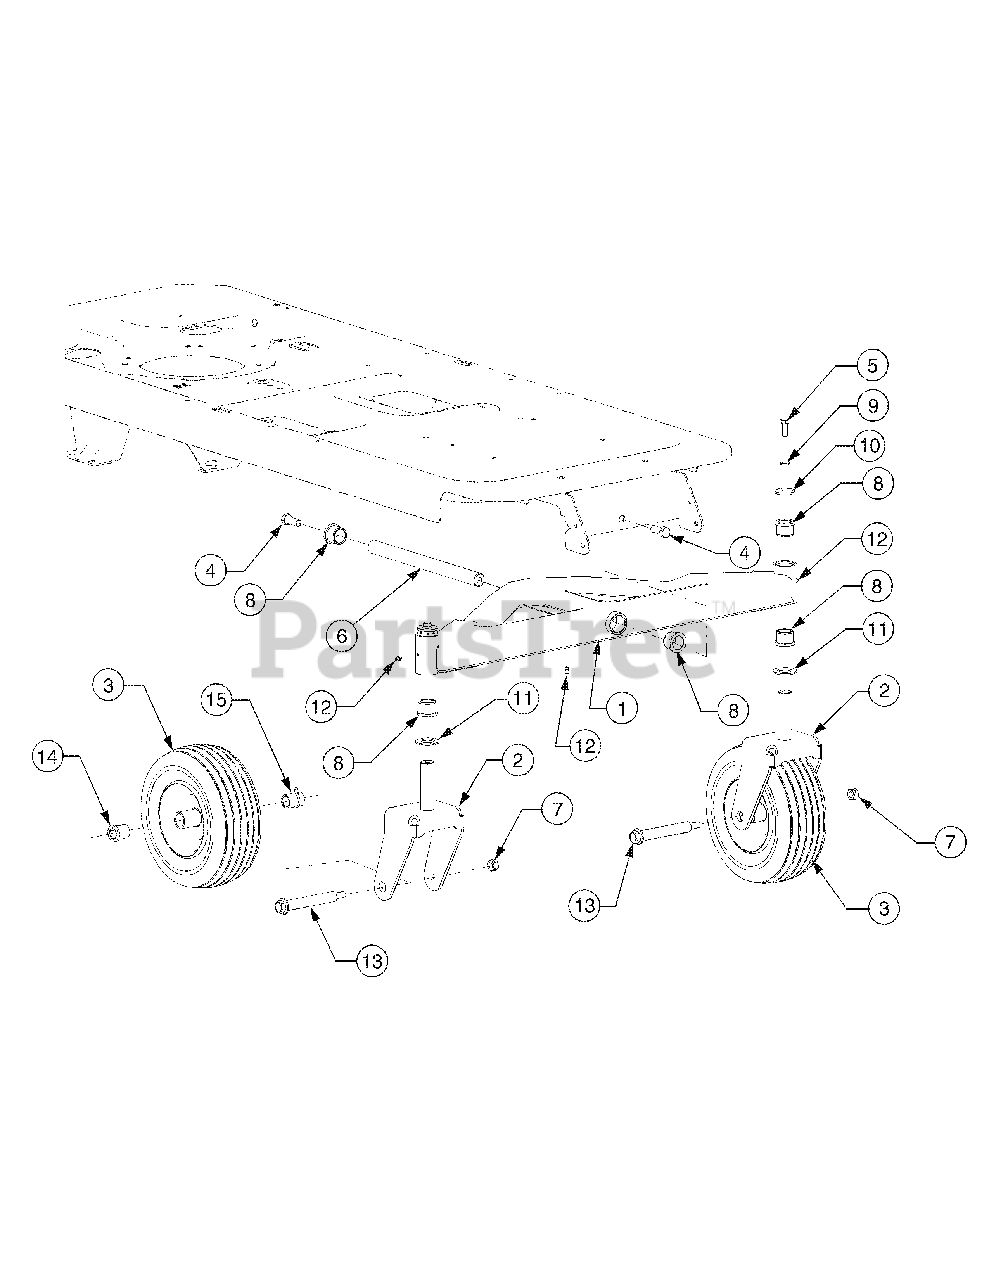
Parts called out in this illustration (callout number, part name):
3	Wheel Ass’y 11 .0 x 4.0 x 5.0 Beige
3	Wheel Ass’y 11 .0 x 4.0 x 5.0 Yellow
4	Hex Lock Screw 1/2-13 x 1.25 Gr. 5
5	Hex Screw 3/16 x 1.00
6	Axle Shaft
7	Hex Cent. L-Nut 1/2-13 Thd. Gr. 5
8	Flange Bearing 1.0 x 1,246
9	L-Wash 3/8 ID
10	Flat Washer .39 ID x 1.5 OD x .135
11	Flat Washer
12	Grease Fitting
13	Shoulder Screw .75 x 4.75:7/16-14
14	Flange Brg. .75" ID
15	Flange Brg. .76 ID w/Lube Ftg.
